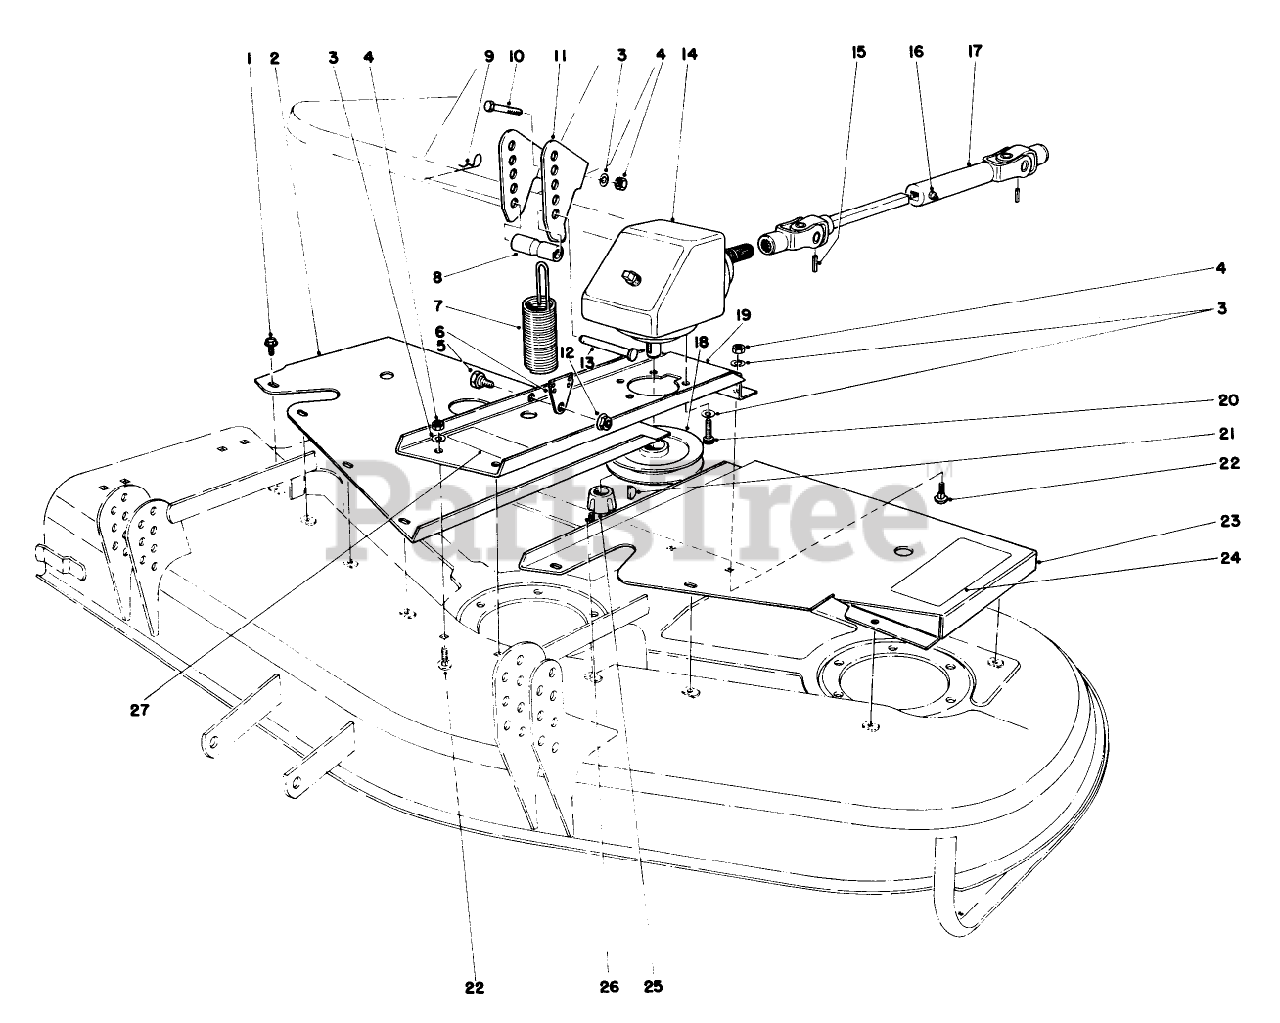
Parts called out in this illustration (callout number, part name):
1	SCREW-HHFTF
2	RH COVER WA R
3	WASHER-LOCK
4	NUT-HEX
5	BOLT-SHOULDER
6	SPRING END R
7	Spring-Extension
8	SPACER
9	PIN-HAIR
10	SCREW-HH
11	SPRING BRACKET R
12	NUT-HHF, WHIZ
13	PIN-CLEVIS
14	GEAR BOX ASM
15	PIN-ROLL
16	FITTING-GREASE
17	UNIVERSAL JOINT
18	PULLEY WA BO
19	Base-Bear Box
20	SCREW-HSH
21	KEY-WOODRUFF
22	SCREW-CARR
23	LH COVER WA R
24	DECAL
25	BUSHING-LOCK, TAPER
26	SCREW-SET, HSH
27	Decal-Caution
